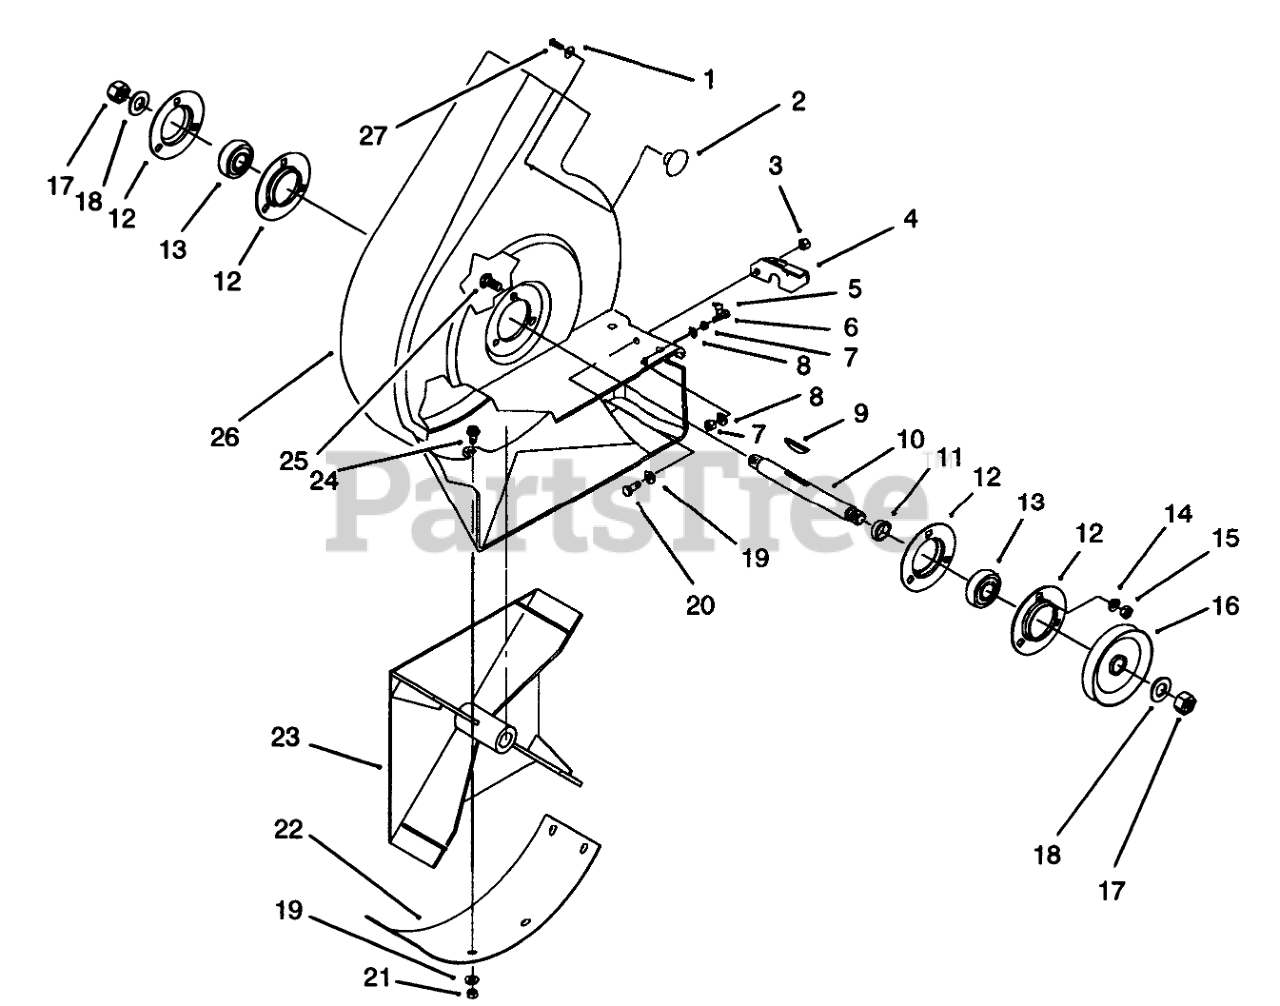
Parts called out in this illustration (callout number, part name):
1	WASHER-PLAIN
3	NUT-LOCK, NI
4	42" BLOWER LATCH B
5	SPRING-EXTENSION
6	SCREW-HWH
7	NUT-HEX
8	WASHER-FLAT
10	SHAFT-BLOWER
11	Spacer
12	FLANGE
13	BEARING-BALL
14	WASHER-LOCK
15	NUT-HEX
16	PULLEY-BLOWER
17	NUT-JAM
18	WASHER-LOCK
19	WASHER-FLAT
20	SCREW-HH
21	NUT-LOCK, NI
22	COVER-BLOWER, BOTTOM
23	Impeller
24	SCREW-CARRIAGE
25	BOLT-CARR
26	HOUSING-VAC, BLOWER
27	SCREW-PPHTF
